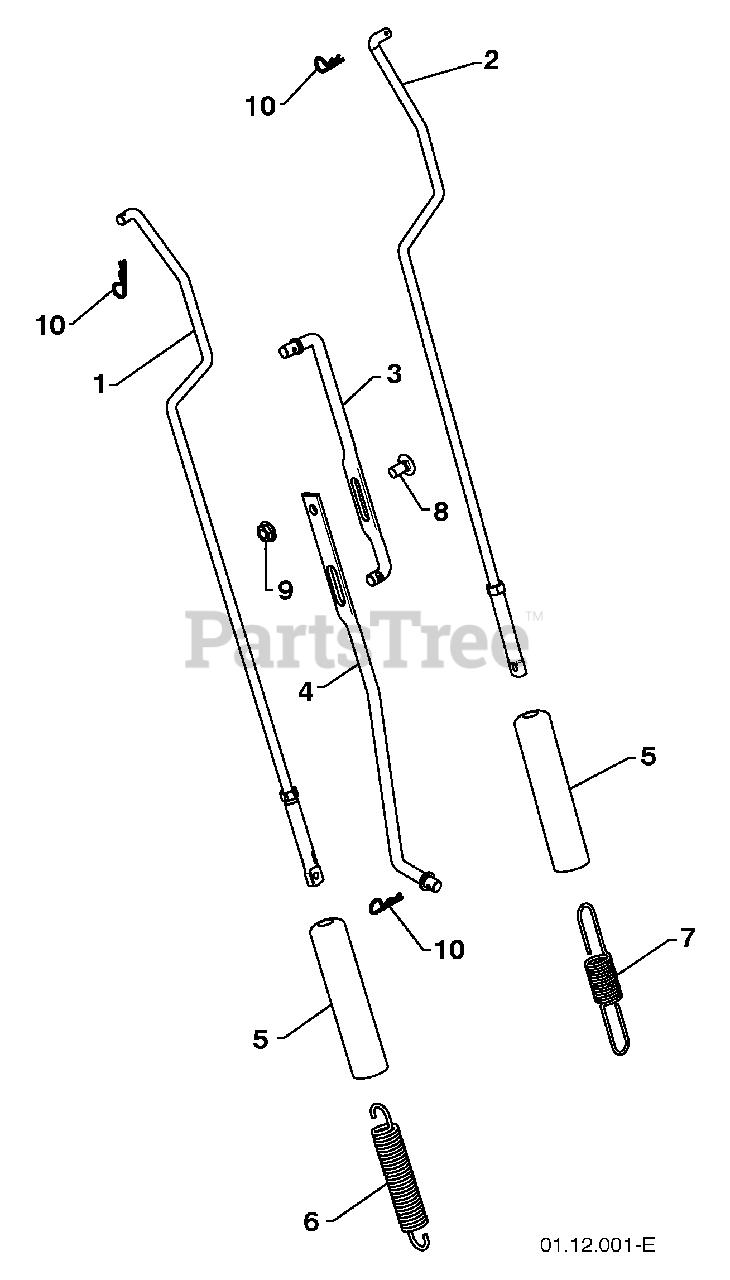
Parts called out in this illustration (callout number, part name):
1	IMPELLER ROD ASSEMBLY
2	TRACTION ROD ASSEMBLY
3	SHIFTER ROD TOP
4	SHIFTER ROD BOTTOM
5	SPRING SLEEVE
6	IMPELLER SPRING
7	TRACTION SPRING
8	CARRIAGE BOLT 5/16-18 X .75
9	NUT 5/16-18
10	RETAINER
